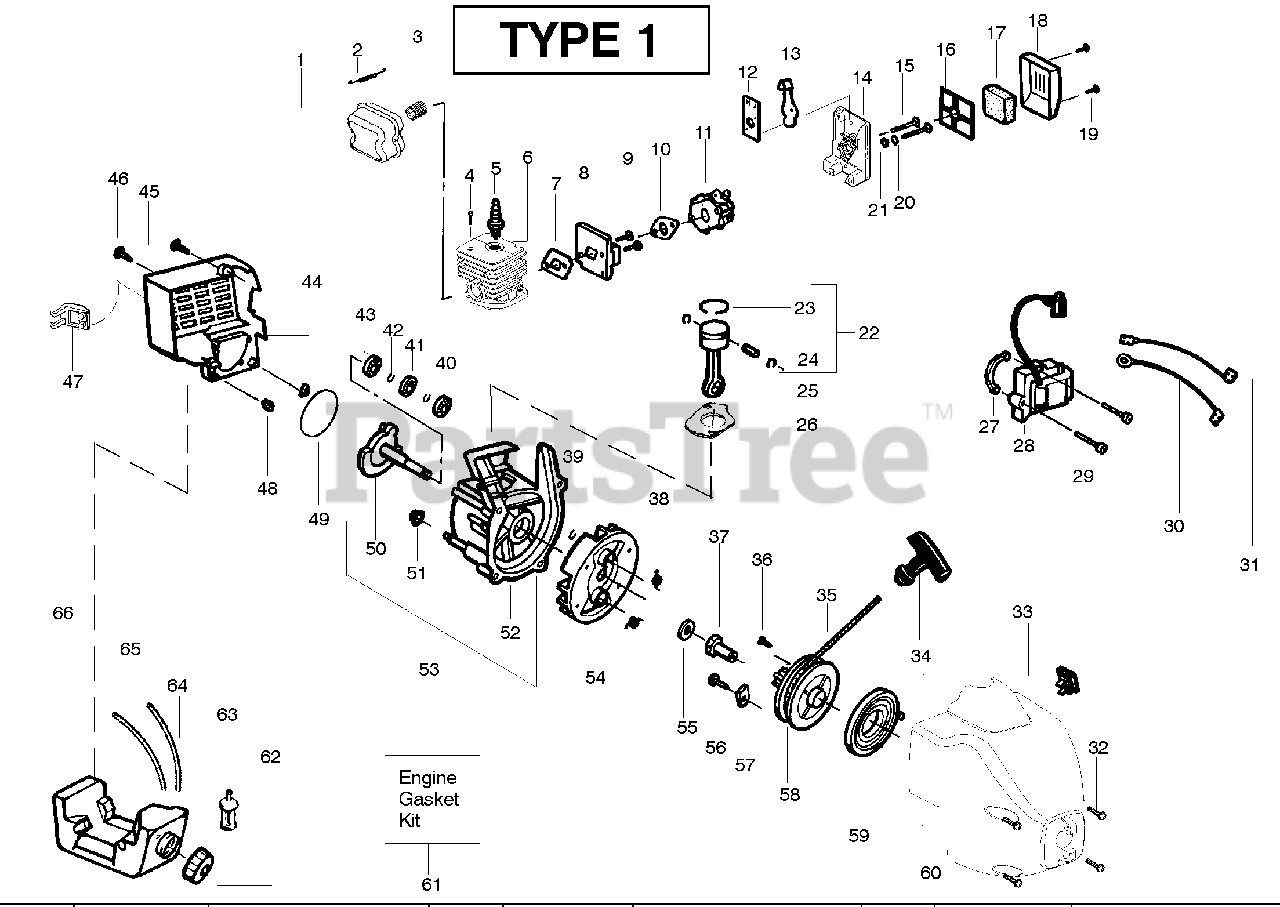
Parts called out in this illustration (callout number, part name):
1	Kit-Muffler
2	Muffler Spring
3	Screen-Spark Arrestor
4	Screw-Cylinder
5	Spark Plug (RCJ 8Y)
6	Kit - Cylinder
7	Gasket-Cylind./Carb.
8	Kit - Carb. Adaptor
11	Kit - Carburetor Ass'y
12	Choke Plate Mounting
13	Choke Shutter
16	Plate - Filter Support
17	Air Filter Foam
18	Air Filter Cover
22	Kit - Piston
23	Piston Ring
24	Piston Pin Retainer
25	Connecting Rod Ass'y.
26	Gasket-Cylinder
27	Spacer-Module
28	Ignition Module
30	Ground Wire Ass'y.
31	Lead Wire Ass'y.
32	Screw
34	Starter Handle
37	Drive Coupling
38	Starter Dog Spring
39	Retain. Ring-C'shaft
40	Outer Bearing
42	Retainer Ring-C'case
43	Inner Bearing
44	Rear Shroud
46	Screw
47	Guard-Muffler
48	Isolator-Shroud
49	O-Ring-C'case/Shrd
50	Crankshaft Ass'y.
51	Isolator-Crankcase
52	Crankcase Ass'y.
53	C'case & C'shaft Assy.
54	Flywheel Ass'y.
58	Starter Pulley Kit
59	Starter Spring
60	Assy. - Fan Housing
61	Kit-Engine Gasket
62	Fuel Cap Ass'y.
63	Fuel Pickup Ass'y.
64	Kit-Fuel Line (Small)
65	Kit-Fuel Line (Large)
66	Fuel Tank Ass'y
